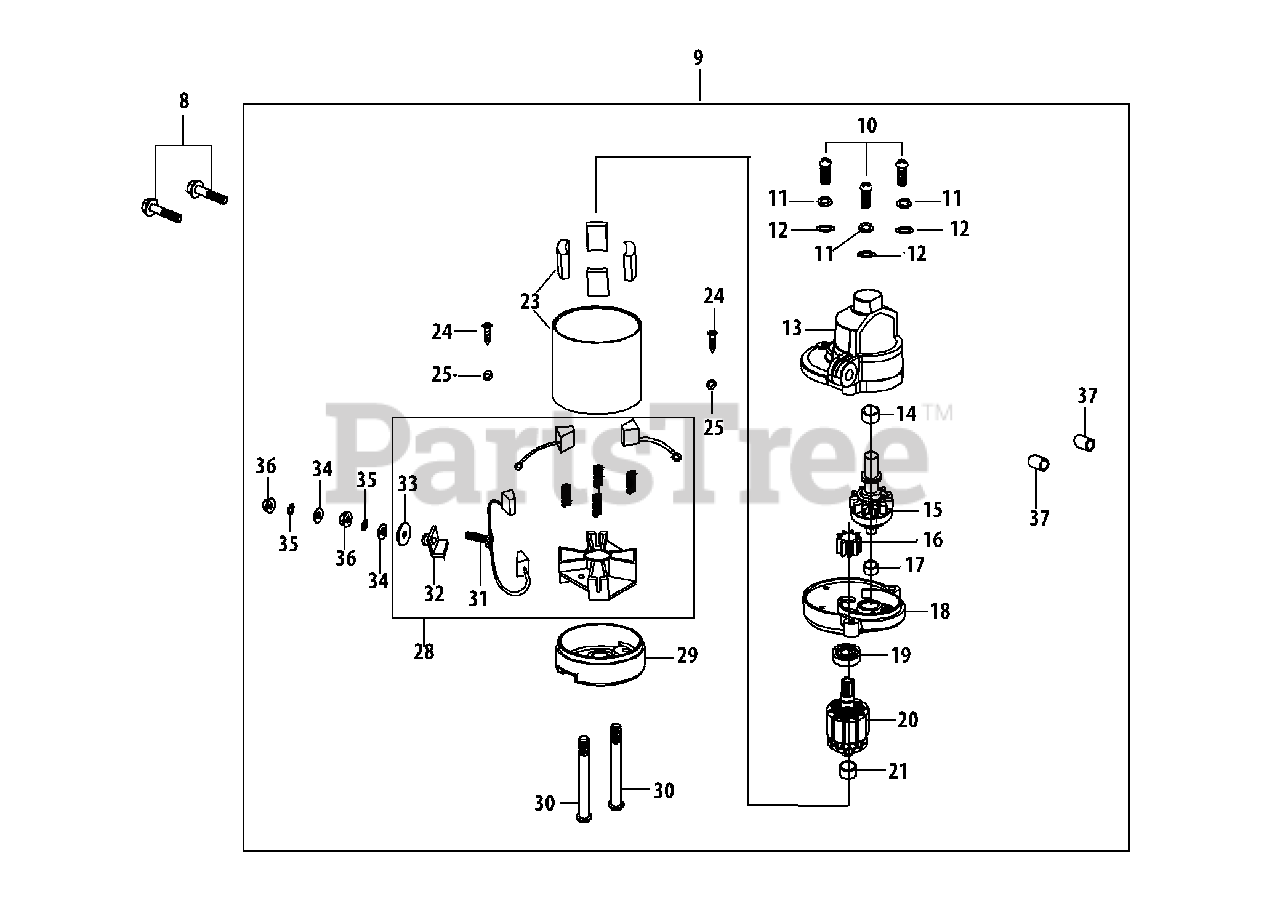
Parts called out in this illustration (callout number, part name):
8	Bolt M8×40
9	Starter Assembly
10	Screw M5×25
11	Lock Washer
12	Plain Washer
13	Electrical Starter Front Cover
15	Pinion/Clutch Assembly
18	Pinion Cover
19	Bearing 6001Zz
20	Starter Armature
23	Starter Housing Assembly
25	Lock Washer
28	Brush Assembly
29	Electrical Starter Back Cover
30	Bolt M6×100
31	Bolt M6×30 Assembly
32	Waterproof Washer
33	Insulation Washer
34	Plain Washer
35	Lock Washer
36	Nut M6
37	Dowel Pin 10×14
